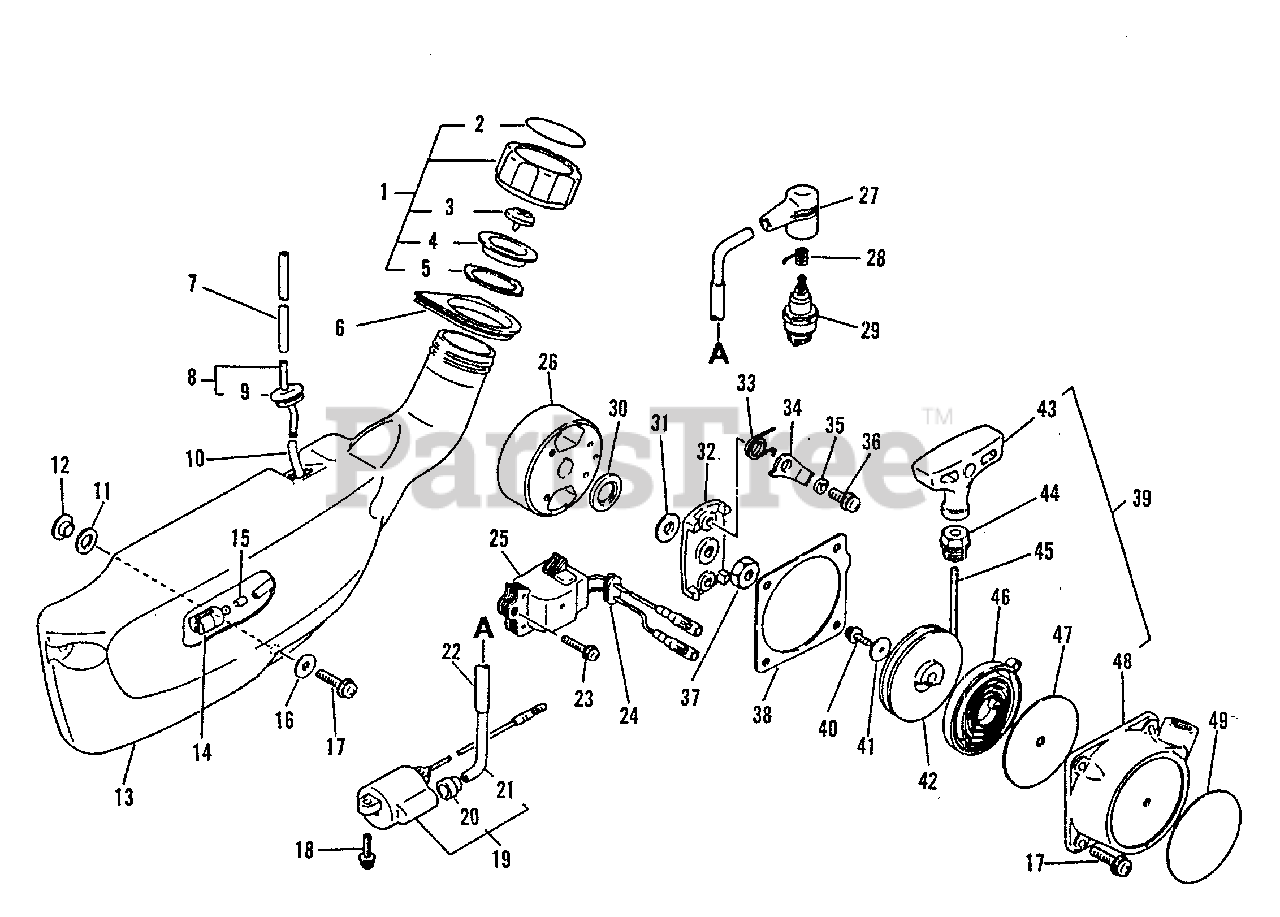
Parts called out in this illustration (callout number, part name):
1	CAP ASSY
2	LABEL - FUEL MIX
4	HOLDER, VENT
5	GASKET, CAP
6	BUSHING
7	PIPE - FUEL
8	CONNECTOR
10	PIPE - FUEL
11	WASHER - RUBBER
13	TANK, FUEL
14	FILTER, FUEL
17	SCREW - 5X20
18	SCREW - 4X14
19	COIL, IGNITION
20	CORD, HIGH TENSION
21	CORD, HIGH TENSION
23	SCREW - 4X20
25	COIL, IGNITION
26	FLYWHEEL
27	CAP, SPARK PLUG
28	TERMINAL, SPARK PLUG CAP
29	SPARK PLUG -- BPM-7A
31	WASHER - 8
32	CATCHER, PAWL
33	SPRING, RETURN
34	PAWL, STARTER
36	SCREW - 5X40
37	NUT - 8 -- LEFT HAND
38	GASKET, STARTER
39	STARTER ASSY
40	SCREW - 4X10
42	REEL, ROPE
43	GRIP, STARTER
44	GUIDE, ROPE
45	ROPE, STARTER - 3X850
46	SPRING, REWIND
47	PLATE, STARTER
48	CASE, STARTER
49	LABEL - ECHO
